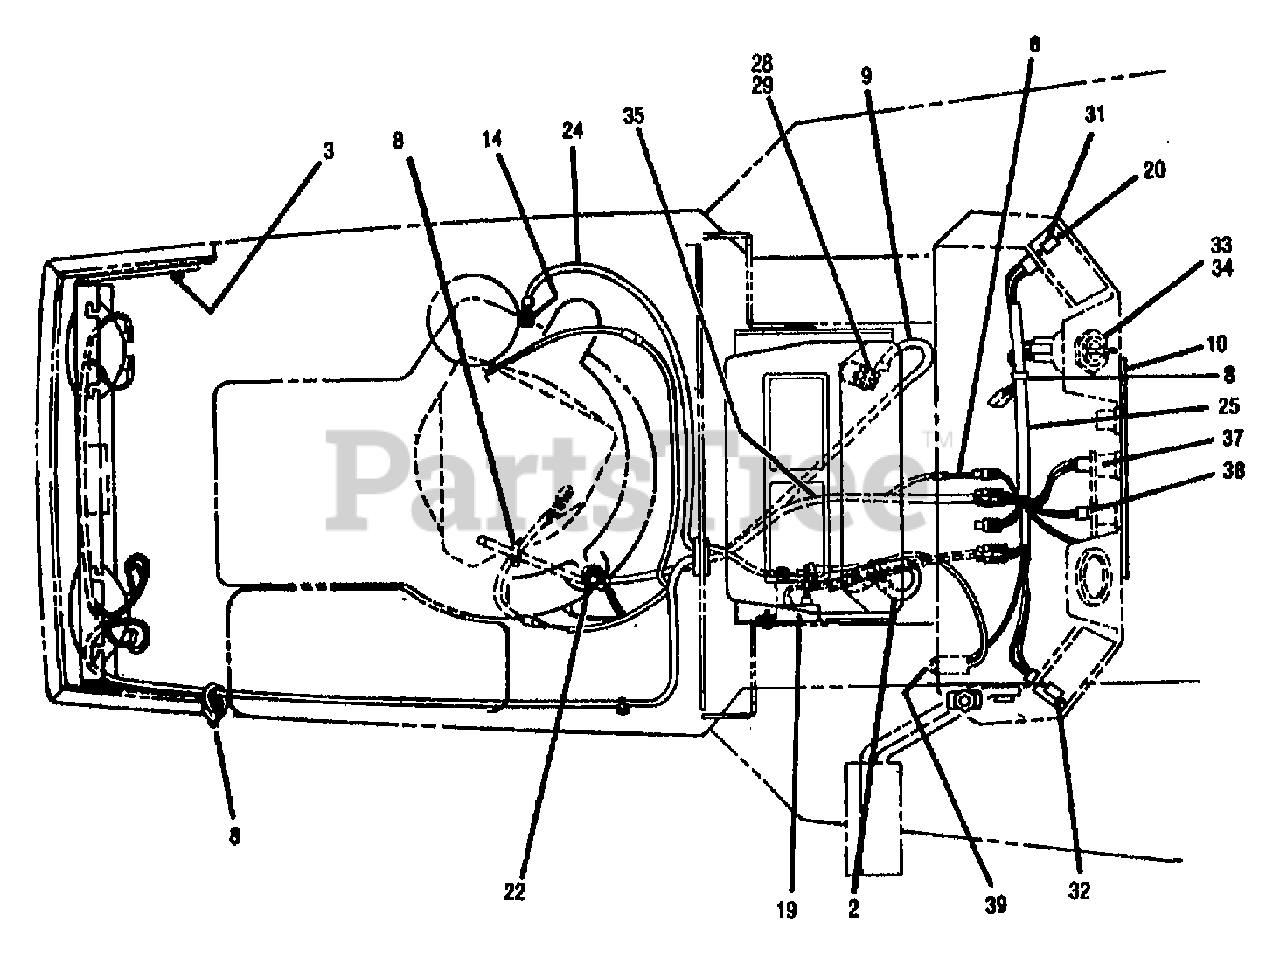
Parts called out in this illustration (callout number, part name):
2	CABLE-BATTERY (+)
3	NUT-HF/LK 1/4-20 ZP
6	ASSM-DIODE
8	TIE-CABLE NYLON BLACK
9	CABLE-BATTERY (-)
10	LENSE
14	NUT-HT LK 1/4-20
19	SOLENOID
20	SCR-FHP #6-32X.50 ZP
24	CABLE-STARTER
25	HARNESS-CONSOLE WIRING
31	SWITCH-PTO
32	SWITCH-LIGHT
33	SWITCH-IGNITION
34	KEY-IGNITION
35	HARNESS-WIRE ENGINE {3312GR,3312GRS}
37	BULB (MFG NO. GE 73)
38	SCR-PHP M6-32X.38 ZP
39	FUSE-30 AMP
